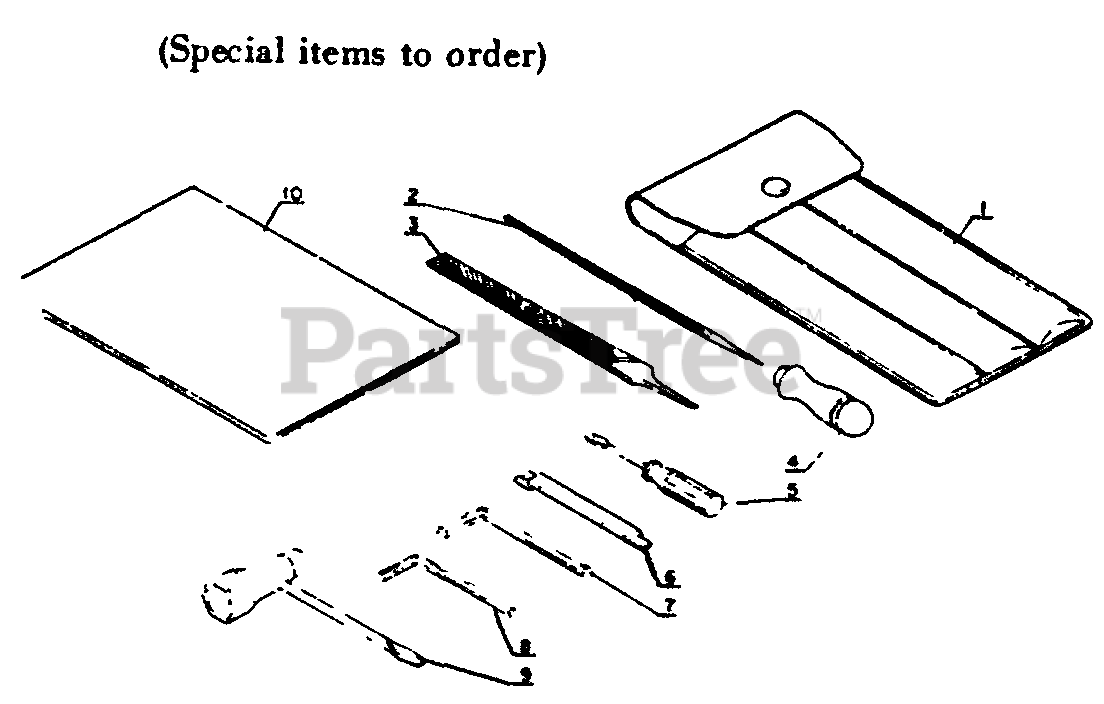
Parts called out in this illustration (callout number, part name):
1	BAG, TOOL
2	FILE - ROUND
3	FILE - FLAT
4	FILE GRIP
5	SCREWDRIVER - 50mm
6	DEPTH GAUGE
7	HEX KEY - 4mm
8	HEX KEY - 3mm
9	T-WRENCH - 10X19mm
10	Operator manual
